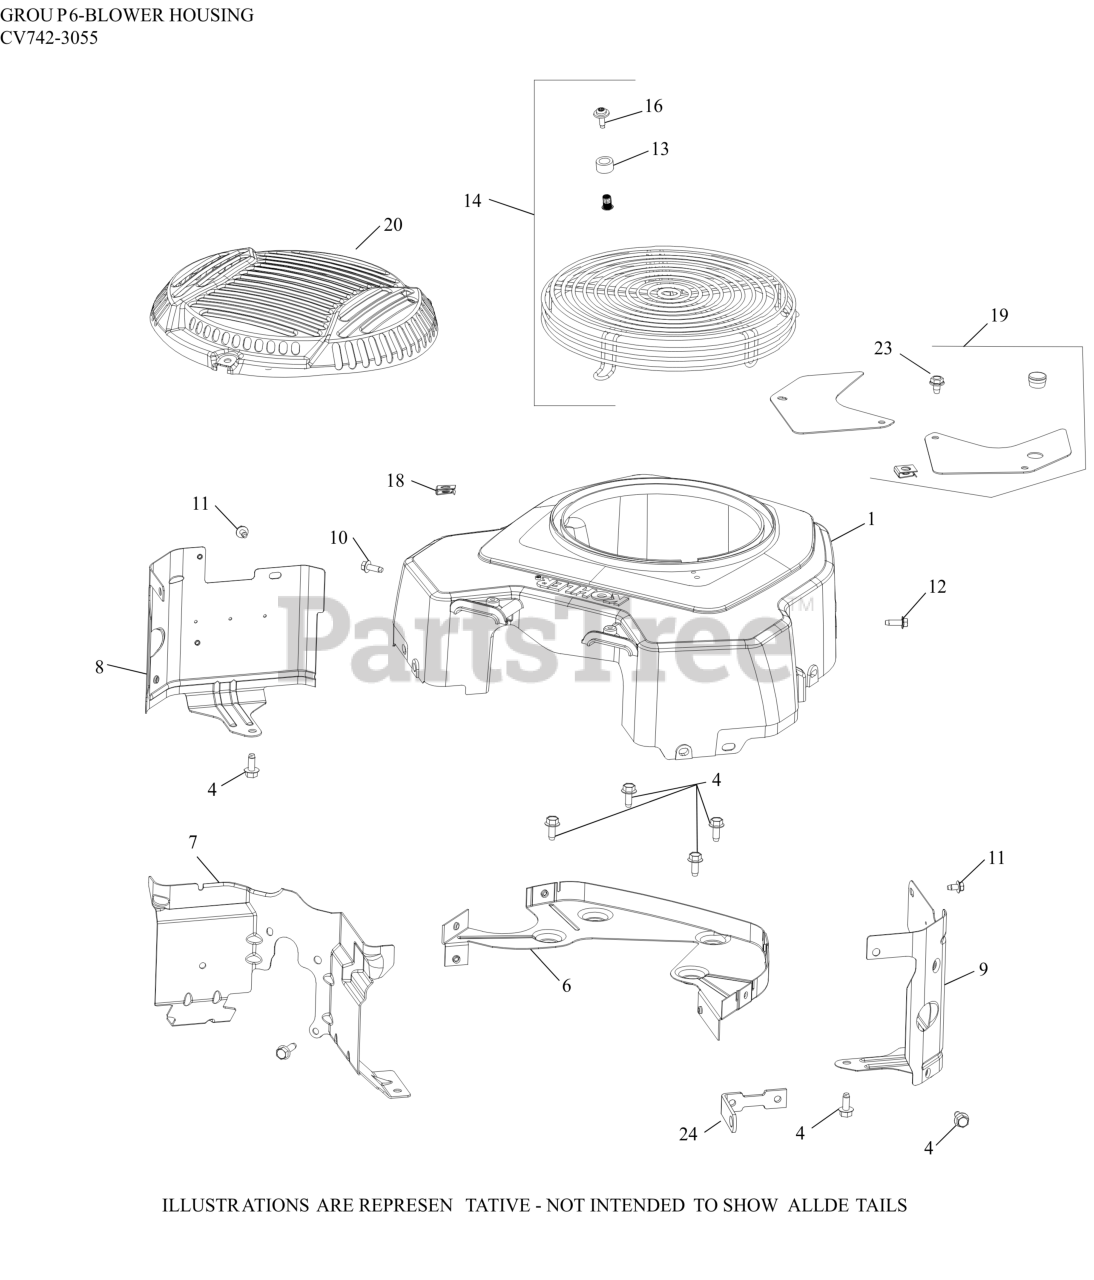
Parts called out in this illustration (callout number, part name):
1	HOUSING, BLOWER
4	SCREW, THREAD FORMING
6	KIT, BACKING PLATE
8	KIT, CYL BAFFEL #1 SIDE
9	BAFFLE, LEFT BARREL
10	SCREW, THREAD FORMING
11	SCREW, THREAD FORMING
12	SCREW, THREAD FORMING
14	INSERT, THREADED (M5)
16	SCREW, SEMS
18	CLIP, BAFFLE MOUNTING
19	KIT, ACCESS PANEL
20	GUARD, GRASS SCREEN (METAL)
23	SCREW, THREAD FORMING
24	STRAP, LIFTING
